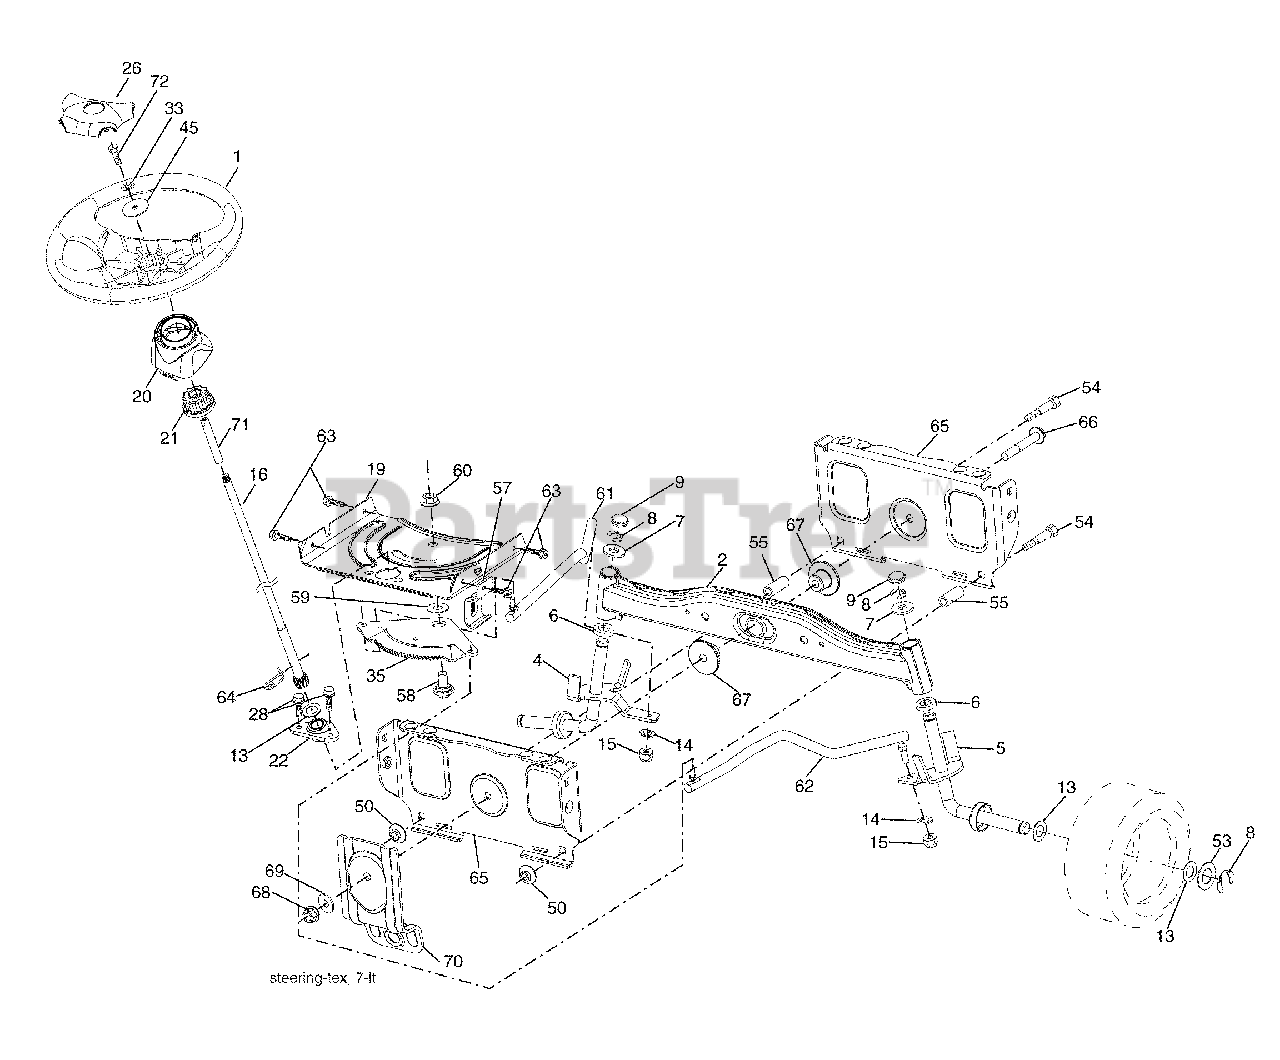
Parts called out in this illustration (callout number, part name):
1	Wheel, Steering
2	Axle Asm., Front
4	Spindle Asm., LH
5	Spindle Asm., RH
6	Bearing, Race Thrust Harden
7	Washer 25/32 x 1-5/8 x 16 Ga.
8	Ring, Klip #T5304-75
9	Cap, Spindle
13	Washer 25/32 x 1-1/4 x 16 Ga.
14	Washer, Lock Hvy Hlcl Spr 3/8
15	Nut, Crown Lock 3/8-24 unf
16	Shaft Steering
19	Plate Steering
20	Boot, Steering
21	Adapter, Wheel Steering
22	Bushing, Strg. Blk
26	Insert, Wheel Steering
28	Screw 3/8-16 x 3/4
33	Washer Lock 5/16
35	Gear, Sector Plate
45	Washer 11/32 ID x 2-3/8 x 12 Ga.
50	Nut Lock 3/8-16 unc
53	Washer Hardened .793 x 1.637 x .060
54	Bolt Hex 3/8-16 unc x 2-1/4
55	Spacer Brace Axle
57	Bracket Upstop
58	Bolt Shoulder Sector Pivot CFM
59	Washer Thrust Sector Steering
60	Nut Flange Lock 5/8-11
61	Draglink, LH
62	Draglink, RH
63	Screw 5/16-18 x 3/4
64	Retainer Clip Spring Steering
65	Brace Axle Front
66	Bolt Hex Fghd 7/16-14 x 3 Serr
67	Bushing PM Front Axle
68	Nut Lock Flange 7/16-14 Gr. 5
69	Washer 1.5 x .505 x .118
70	Bracket Deck Susp. Front
71	Shaft Ext Steering
72	Bolt 5/16-18 x 4.5 Gr. 5
